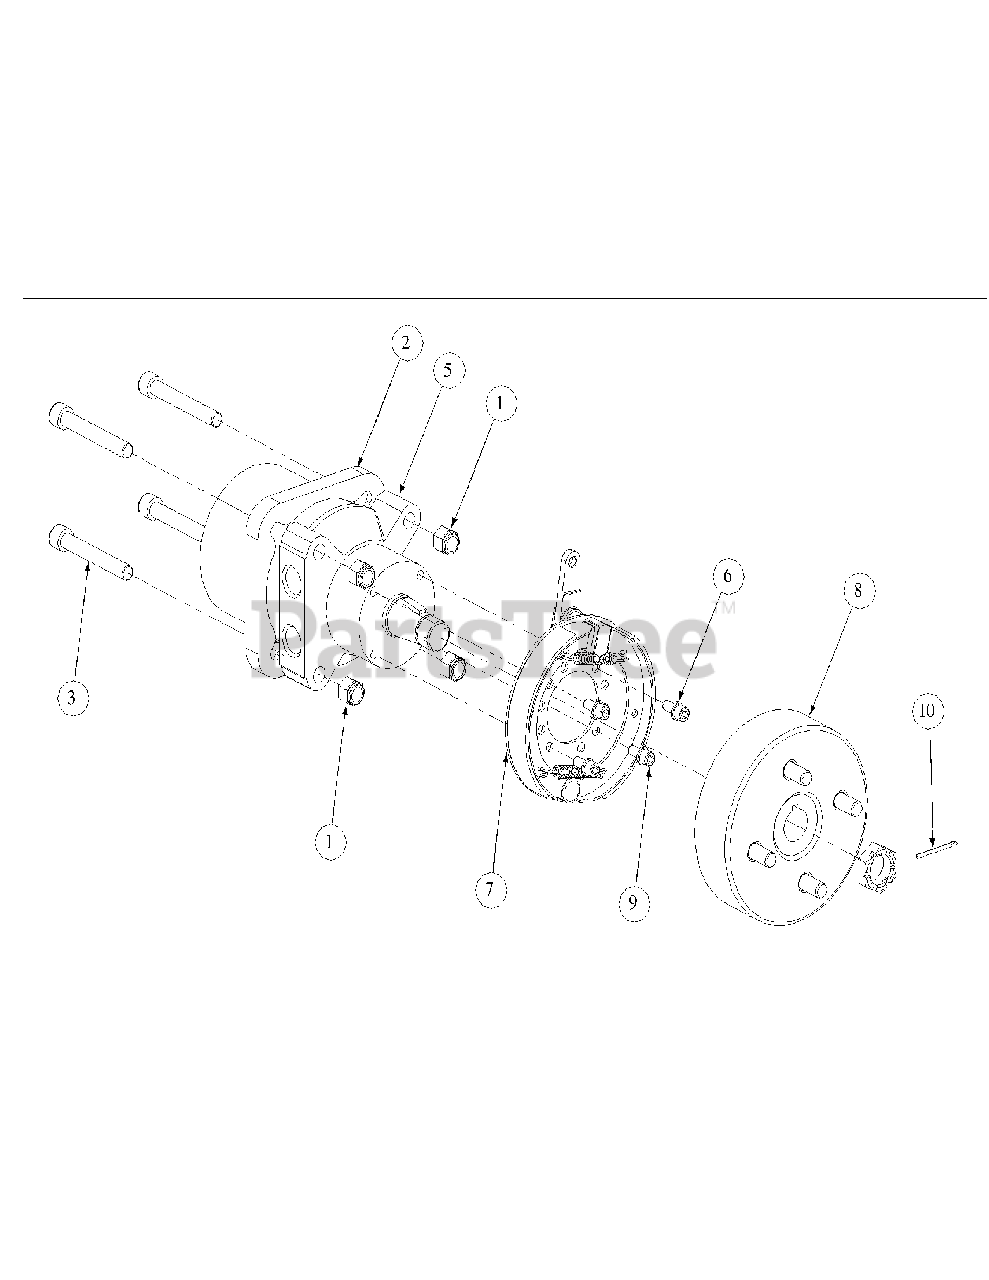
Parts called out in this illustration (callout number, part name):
1	Lock Nut, Nylon Insert, 1/2-13
2	Motor Spacer
3	Socket Head Capscrew, 1/2-13; 6-1/2
4	Hyd. Motor, Parker Left Hand Assembly w/Brake & Drum
5	Hyd. Motor, Parker Right Hand Assembly w/ Brake & Drum
6	Lock Washer, 5/16
7	Brake Assembly w/Line
8	Hub and Drum Assembly w/Studs
9	Capscrew w/Socket, 5/16-18 x 3/4
10	Cotter Pin 1/8 x 1-1/2
